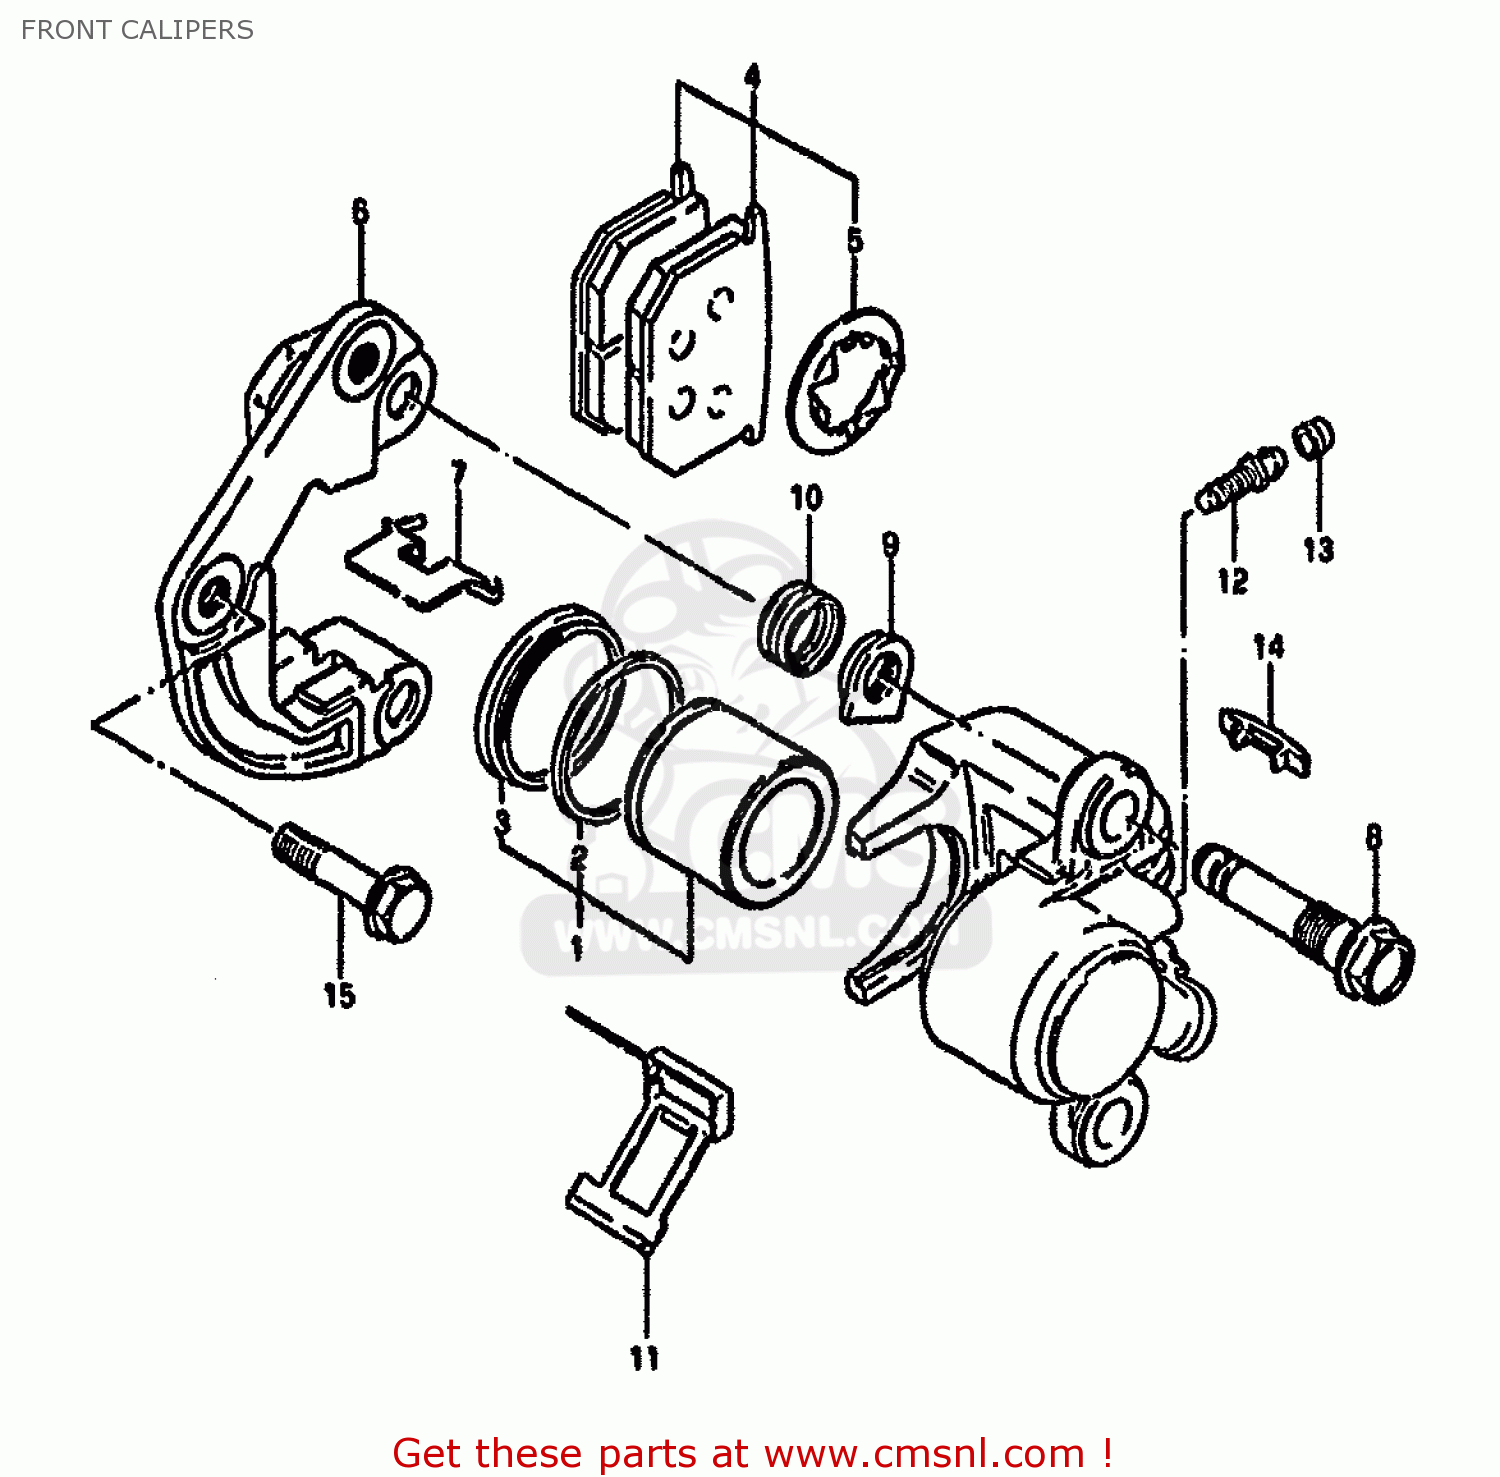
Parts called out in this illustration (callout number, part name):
1	PISTON SET
2	SEAL,PISTON
3	BOOT,PISTON
4	PAD & SHIM SET (MCA)
5	SHIM,PAD
6	HOLDER,CALIPER,LEFT
7	PAD,GUIDE
8	AXLE,CALIPER
9	NUT,CALIPER AXLE
10	BOOT
11	SPRING
12	BREATHER
13	CAP,BLEEDER PL
14	COVER,INDICATOR
15	BOLT 10X37
